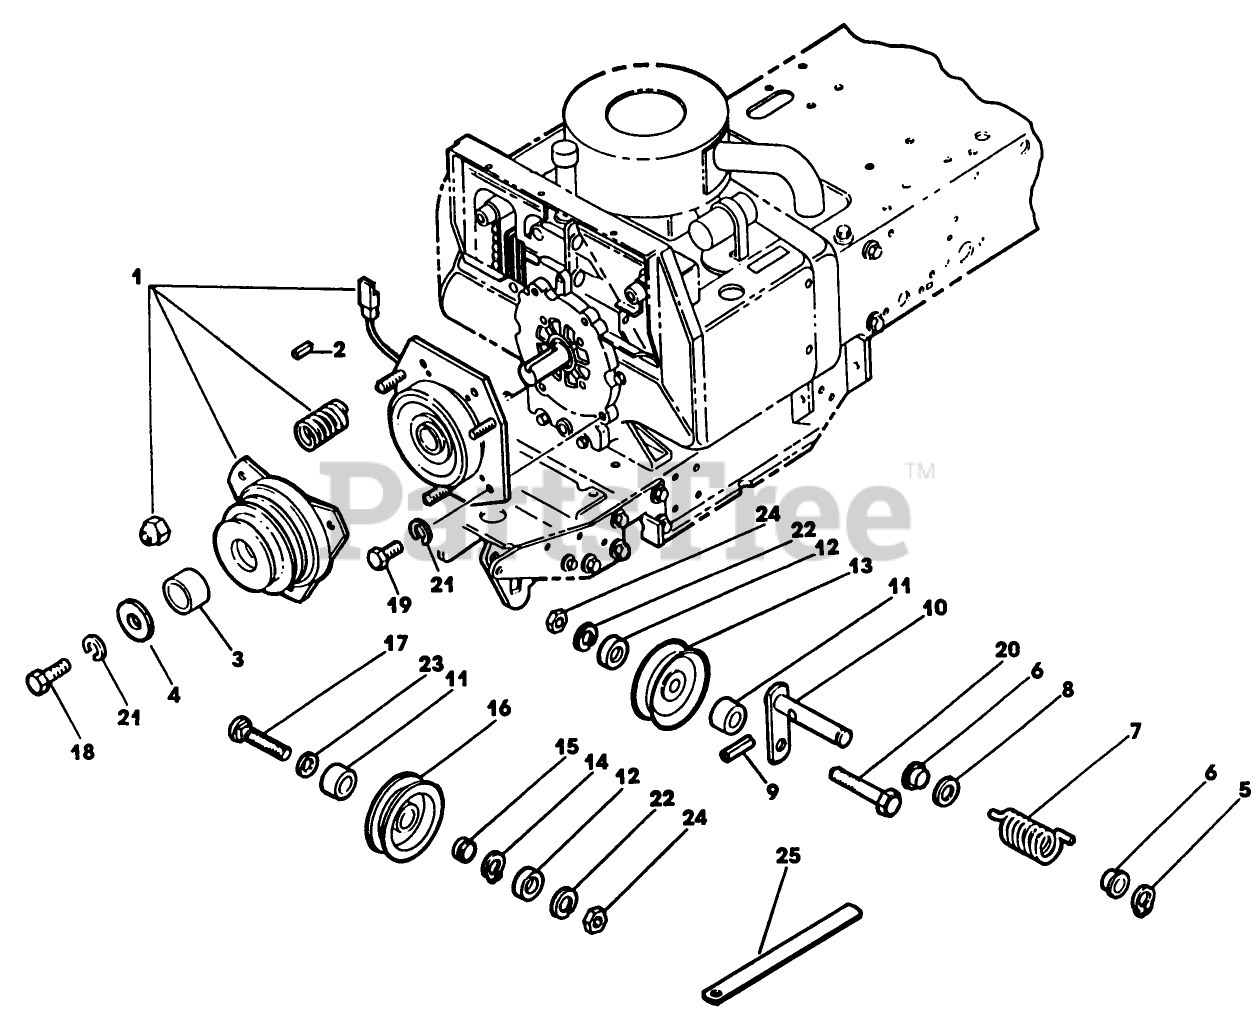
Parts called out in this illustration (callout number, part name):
8	WASHER-SHIM
12	SPACER
13	IDLER PULLEY
14	RING - RETAINING
17	BOLT - CARRIAGE
22	WASHER
